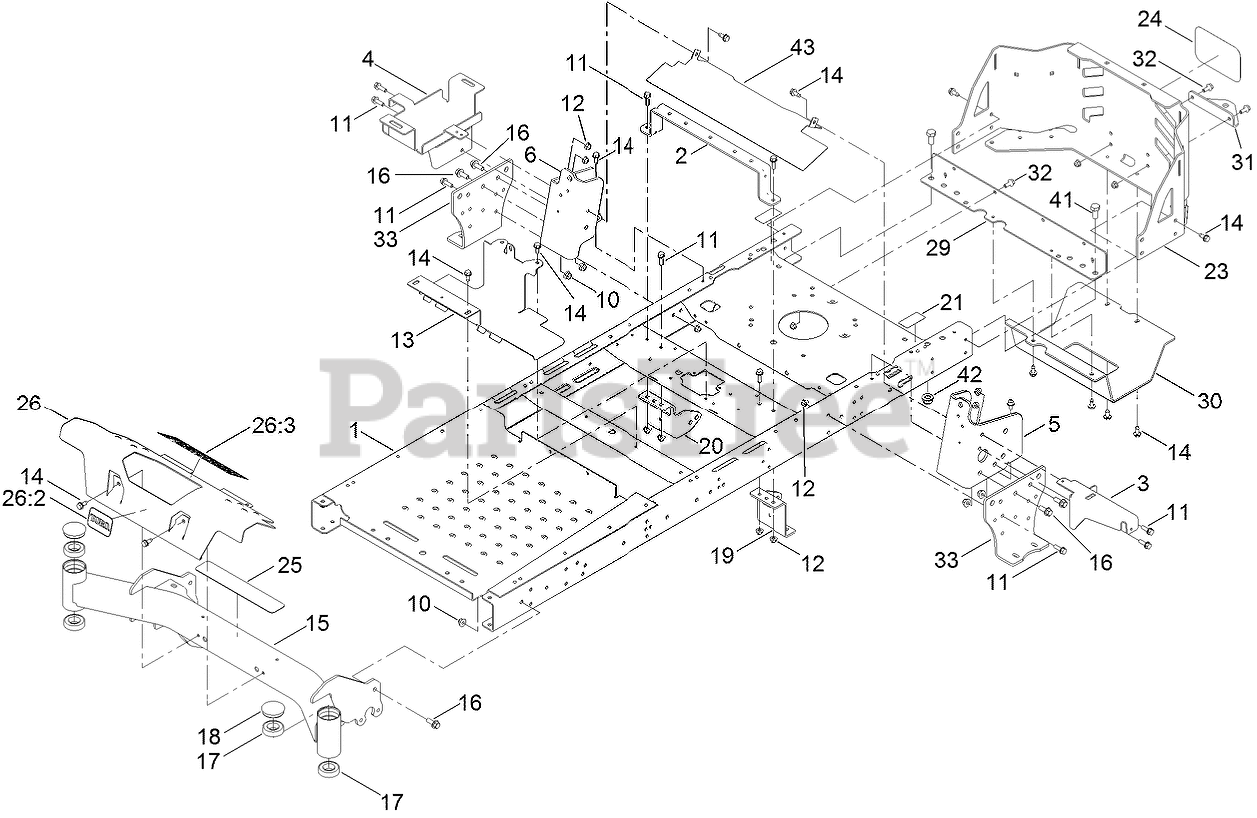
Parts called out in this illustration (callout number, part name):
1	FRAME ASM
2	BRACE-SEAT, REAR (WIDE)
3	BRACKET-SUPPORT, POD (LH)
4	TRAY-BATTERY
5	BRACKET-MOUNTING, LH
6	BRACKET-MOUNTING, RH
10	NUT-HF, NI
11	SCREW-HHF
12	NUT-HF
13	BRACKET-MOUNT
14	SCREW-HWHTF
15	AXLE-FRONT
16	SCREW-HHF
17	BEARING-BALL
18	CAP-GREASE
19	MOUNT-HYDRO, FRONT (LEFT)
20	MOUNT-HYDRO, FRONT (RIGHT)
21	DECAL-BYPASS
23	GUARD-ENGINE
24	DECAL
25	TREAD-STEP
26	FOOTREST
26:3	DECAL-DANGER
29	CROSSMEMBER-REAR, WIDE
30	GUARD-MUFFLER
31	BRACKET-HITCH
32	SCREW-HHF
33	MOUNT-HYDRO
41	SCREW-HH
42	NUT-HF
